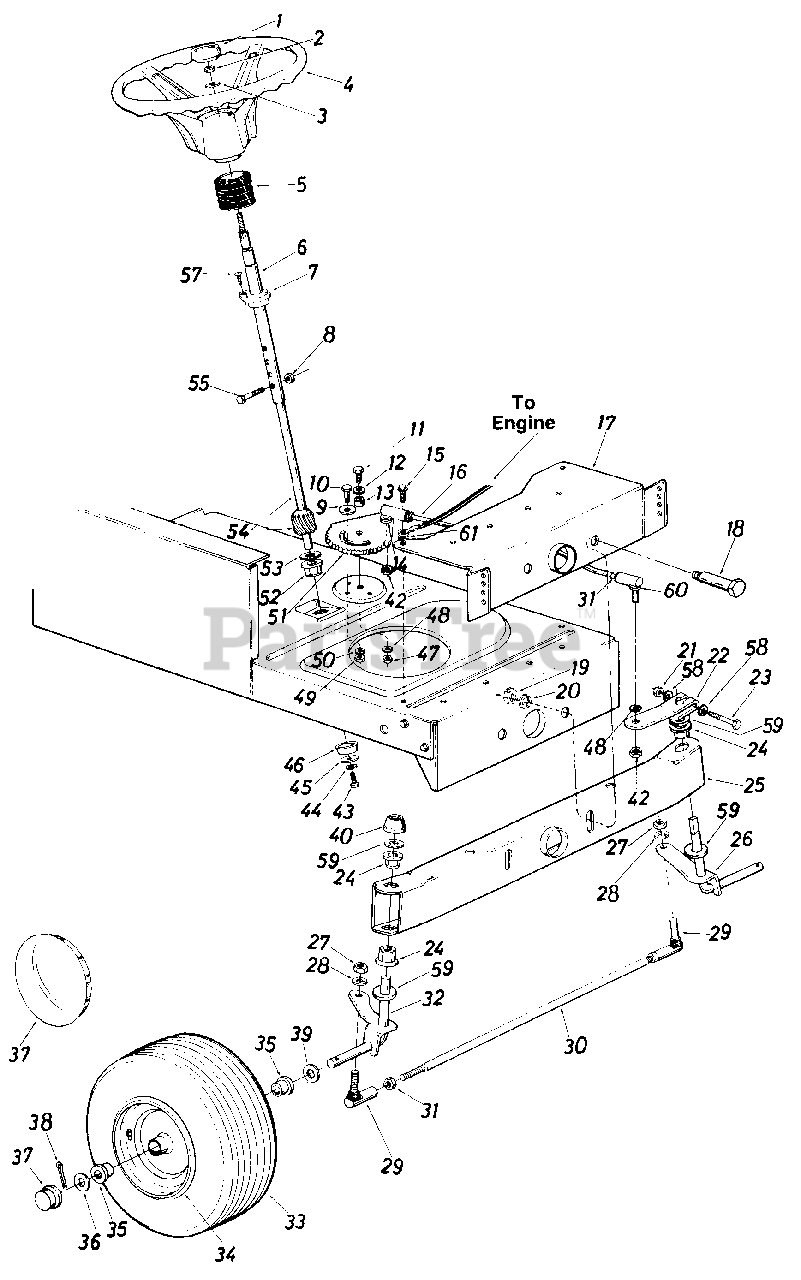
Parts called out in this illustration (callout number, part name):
1	Steering Wheel Cap
2	Hex L-Nut 5/16-24 Thd.
3	Belleville Wash. .345" I.D.
4	Steering Wheel (3 Spoke)
5	Steering Bellow
6	Steering Column Ass'y.
7	Flange Bearing .890 I.D. x 1.36 O.D.
8	Hex L-Nut 1/4-20 Thd.
9	Fl-Wash. .438" I.D. x 1.37"
10	,Shoulder Bolt 437" Dia. x .35 Lg. 5/16-18 Thd.
11	Hex Bolt 3/8-24 x 1.0" Lg.(Grade 5)
12	Bell-Wash. .40" I.D. x 1.13
13	Spacer .380" I.D. x .625" O.D. x .227
14	L-Wash. 3/8" I.D.*
15	Hex Wash. Hd. Self-Tap Scr.
16	Steering Drag Link
17	Front Pivot Brkt.
18	Shoulder Bolt .498" Dia. x 2.04 Lg. 3/8-16 Thd.
19	Hex Nut 3/8-16 Thd.*
20	L-Wash. 3/8" I.D.*
21	Hex Cent. L-Nut 5/16-24 Thd.
22	Steering Arm Front Axle
23	Hex Bolt 5/16-24 x 2.00" Lg.(Grade 5)
24	Hex Flg. Brg. .634 I.D.
26	Front Axle Ass 'y.-L. H .
27	Hex Nut 3/8-24 Thd.*
28	L-Wash. 3/8" I.D.*
29	Ball Joint 3/8-24 Thd.
30	Tie Rod
31	Hex Jam Nut 3/8-24 Thd.
32	Front Axle Ass'y.-R.H.
33	Wheel Ass'y. Comp.
34	Front Wheel Rim Only
35	Bearing
36	Fl-Wash. .635" I.D. x 1.59" O.D.
37	Front Wheel Hub Cap
38	Cotter Pin 1/8" Dia. x 1.25" Lg.
39	Fl-Wash. .640" I.D. x .24" O.D.
40	Push Cap 5/8" Dia. Rod
42	Hex Jam Nut 3/8-24 Thd.
43	Hex L-Bolt 5/16-18 x .62"
44	L-Wash. 5/16" I.D.
45	Fl-Wash. .33" I.D. x 1.25" O.D.
46	Spacer (Plastic)
47	Hex Nut 3/8-24 Thd.
48	L-Wash. 3/8" I.D.
49	Hex Nut 5/16-18 Thd.
50	L-Wash. 5/16" I.D.
51	Steering Gear Segment
52	Hex Flg. Brg. .634 I.D.
53	Fl-Wash. (Hardened)
54	Steering Shaft Lower
55	Hex Bolt 1/4-20 x 1.31" Lg.
57	Oval Hd. Cr.-Sunk Scr. #10 x 5/8" Lg.
58	Wave Wash. .32" I.D. x .62"
59	Fl-Wash. (Hardened)
60	Drag Link Ball Joint 3/8-24 Thd.
61	Ext. L-Wash. 5116" I.D.
